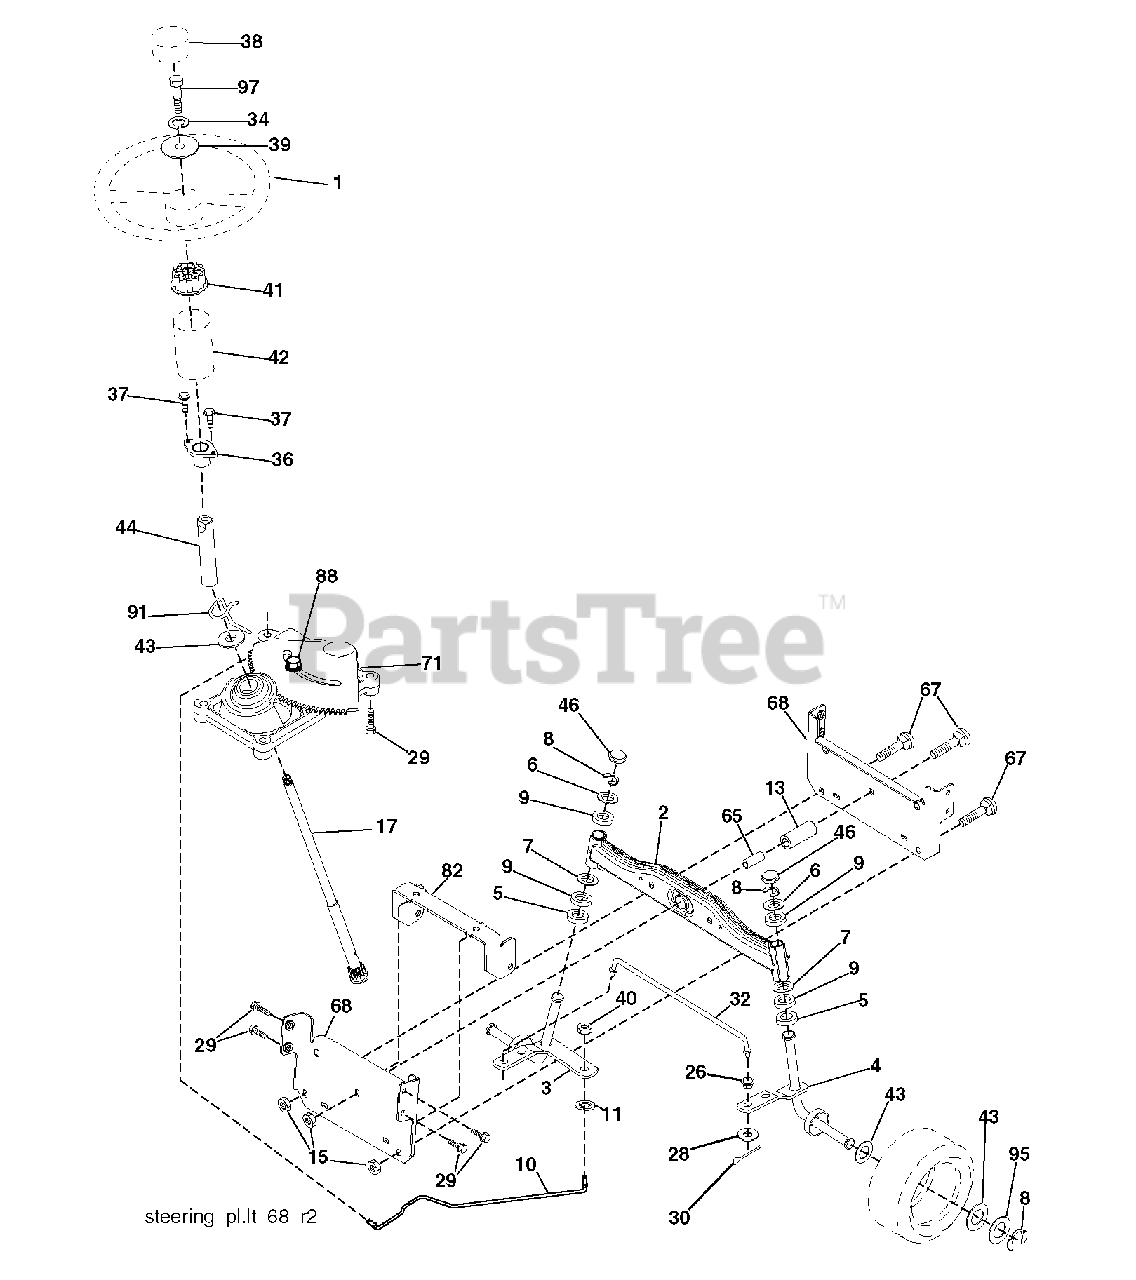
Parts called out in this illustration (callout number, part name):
1	WHEEL.STEERING.OPP.BLACK
2	AXLE HALF ASM-WELDED
3	SPINDLE.ASM.LH.15"TIRES
4	SPINDLE.ASM.RH.15"TIRES
5	THRUST WASHER
9	BRNG T
10	DRAGLINK.15".TIRES.2001
11	WASHER, LOCK 3/8
13	TUBE, PIVOT AXLE (2 2)
15	NUT LOCK FLG 3/8-16 UNC
17	SHAFT STEERING SPLINE
26	BUSHING.DRAGLINK (2 2)
28	WASHER
29	SCREW, 3/8-16X3/4
30	COTTER PIN
32	ROD.TIE.WIRE.FORM
34	LOCKWASHER
36	BUSHING, STEERING
37	SCREW.TT.#10-32X.5.3/8.FLANGE
38	CAP.WHEEL.STEER.OPP.BLK
39	WASHER.11/32
40	NUT CROWNLOCK 3/8-24
41	ADAPTER, WHEEL STNG..
42	BOOT.STEERING.SHAFT.BLACK
44	SHAFT.EXTEN.STRG.SPLINE
46	CAP.SPINDLE.BLACK
65	SPACER.BRACE.AXLE
67	BOLT CARRIAGE
68	BRACE.AXLE.15"TIRES
71	STEERING ASM
82	BRACKET.SUSP.CHASSIS.FRONT.15
88	BOLT, SHOULDER 7/16-20
91	CLIP.STEERING
95	WASHER.HARDENED
97	BOLT 5/16-18 X 4 W/PATCH
